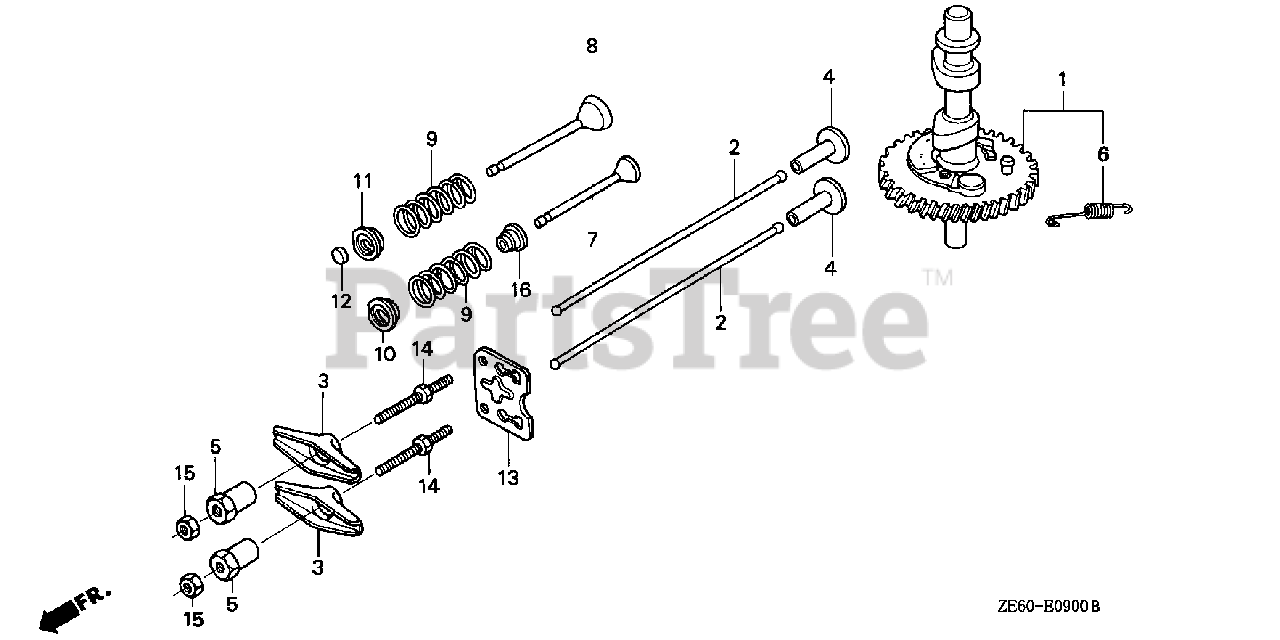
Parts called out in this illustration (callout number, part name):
1	CAMSHAFT ASSY.
2	ROD, PUSH
3	ARM, VALVE ROCKER
4	LIFTER, VALVE
5	PIVOT, ROCKER ARM
6	SPRING, WEIGHT RETURN
7	VALVE, IN.
8	VALVE, EX.
9	SPRING, VALVE
10	RETAINER, IN. VALVE SPRING
11	RETAINER, IN. VALVE SPRING
13	PLATE, PUSH ROD GUIDE
14	BOLT, PIVOT (8MM)
15	NUT, PIVOT ADJUSTING
16	SEAL, VALVE STEM
